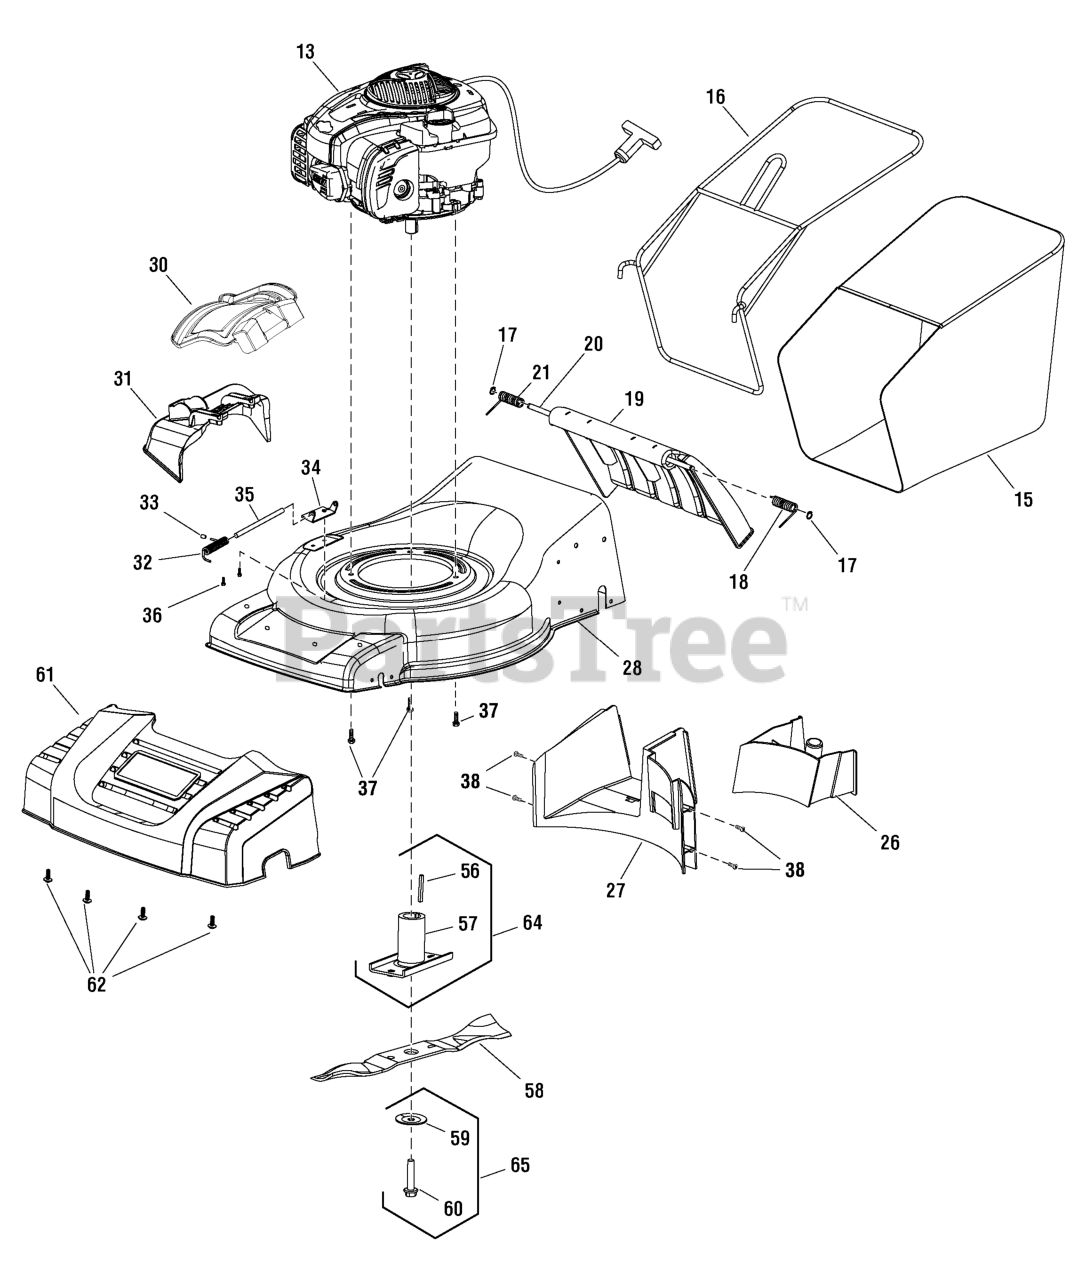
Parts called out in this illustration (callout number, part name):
13	* ENGINE, Briggs & Stratton 550EX Series
15	BAG, Grass
16	FRAME, Grass Bag
17	CIRCLIP
18	SPRING, Left
19	REAR FLAP
21	SPRING, Right
26	MULCH PLUG
27	BAFFLE, Rear
30	COVER, Mulching
31	CHUTE, Side Discharge
32	SPRING, Torsion
33	CAP, Spring
34	BRACKET, Deflector
36	BOLT, M6 x 10
37	BOLT, Self Tapping
38	SCREW, With Washer, ST4.8 x 13
57	ADAPTER, Blade
59	WASHER, Cone
60	BOLT, Blade, 3/8-24 UNF
61	FRONT COVER
62	SCREW, With Washer, ST4.8 x 13
64	KIT, Blade Adapter
65	KIT, Hardware, Blade Bolt
